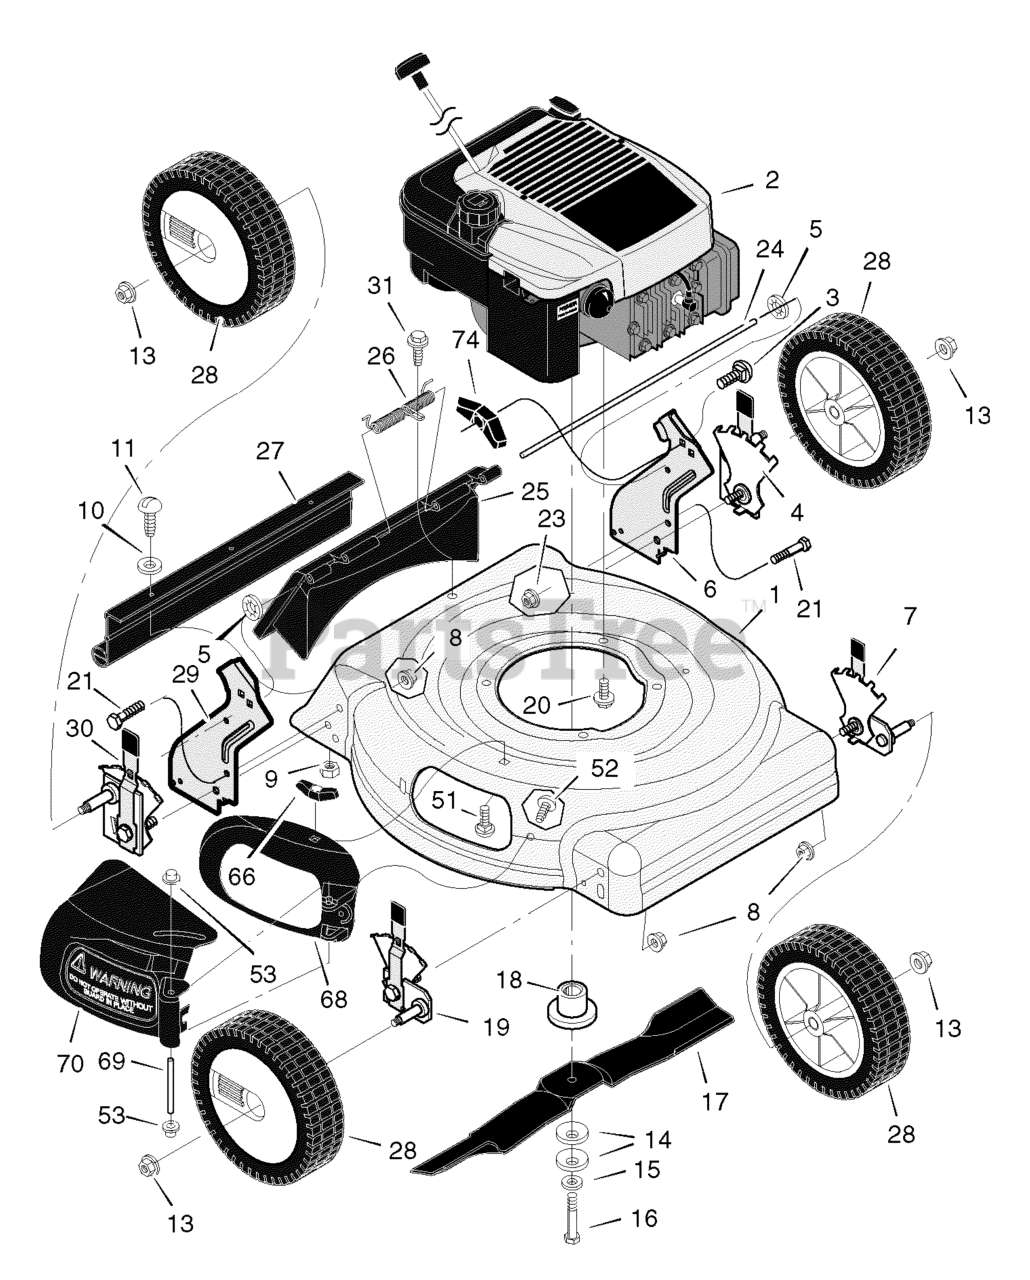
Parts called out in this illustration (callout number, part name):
1	Housing
2	Engine *
3	Bolt, Carriage
4	Adjuster, Left Rear Height
5	Retainer, Push
6	Bracket, Left Handle
7	Adjuster, Left Front Height
8	Nut, Flange
9	Nut, Hex
10	Washer
11	Screw
13	Nut, Flange
14	Washer, Belleville
15	Washer
18	Adapter, Blade
19	Adjuster, Right Front Height
20	Bolt, Engine
21	Bolt
23	Nut, Flange
24	Rod, Pivot
25	Door, Rear (Black)
25	Door, Rear (Gray)
26	Spring
27	Guard, Rear
28	Wheel & Tire *
29	Bracket, Right Handle
30	Adjuster, Right Rear Height
51	Bolt, Carriage
53	Push On Cap
66	Wingnut
68	Bezel (Black)
68	Bezel (Gray)
69	Pin, Pivot
70	Deflector, Chute (Black)
70	Deflector, Chute (Gray)
